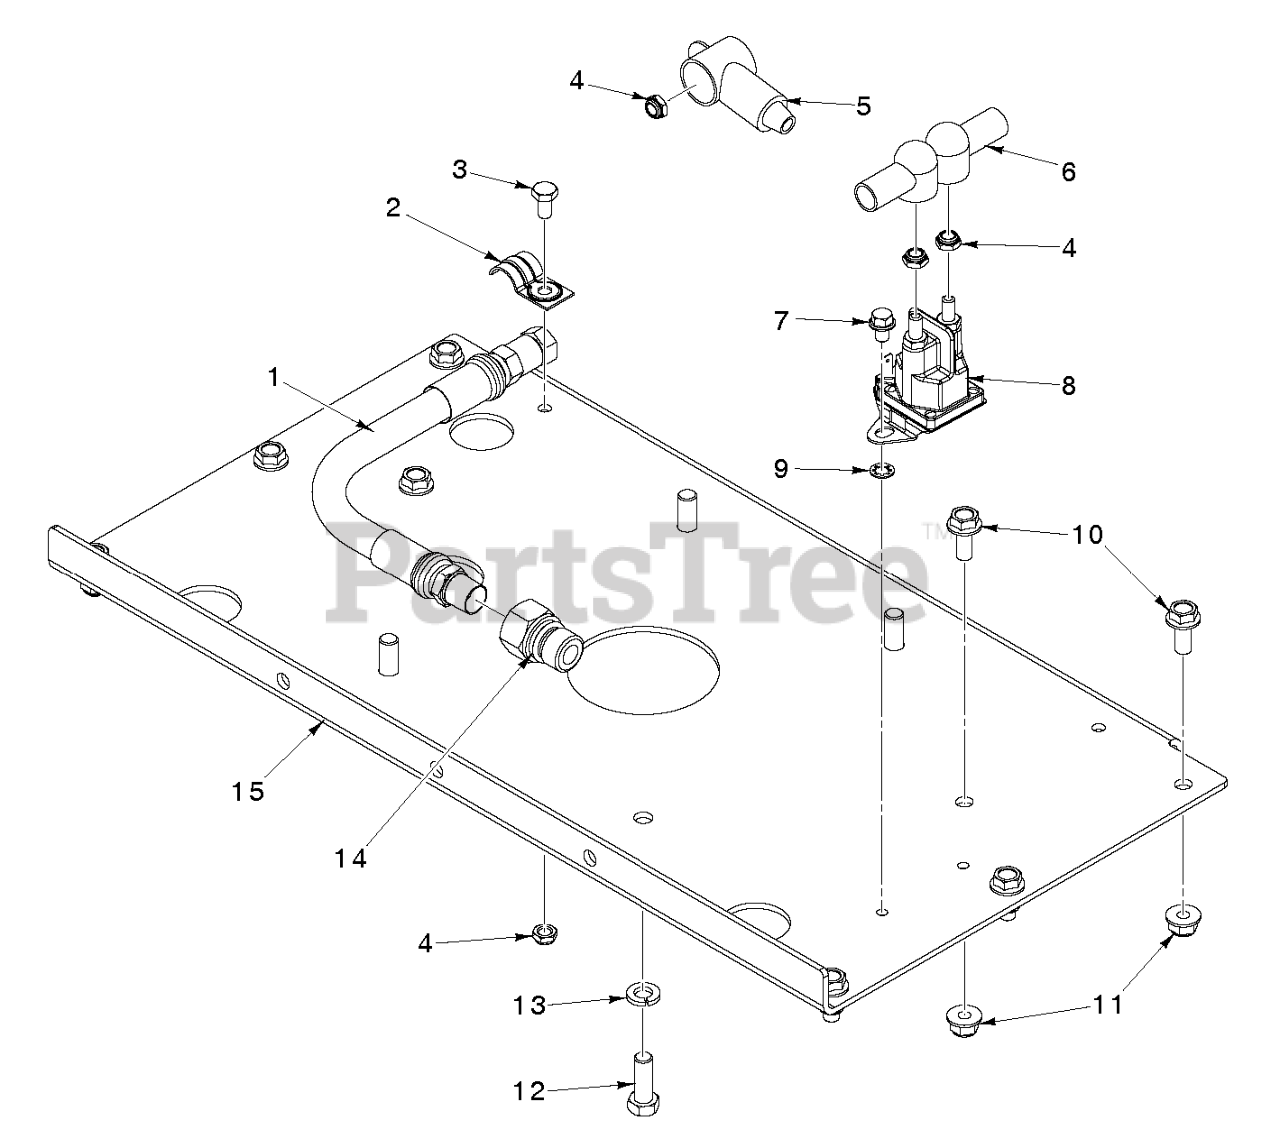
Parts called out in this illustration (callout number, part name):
1	HOSE.ASSEMBLY.OIL.DRAIN
4	Hardware
6	TERMINAL COVER
9	WASHER 1/4 INT TOOTH
11	NUT HEXAGON FLANGE 5/16-18 ST
14	ADAPTER, OIL DRAIN
15	PLATE.PNT.ENGINE.E-DIP
